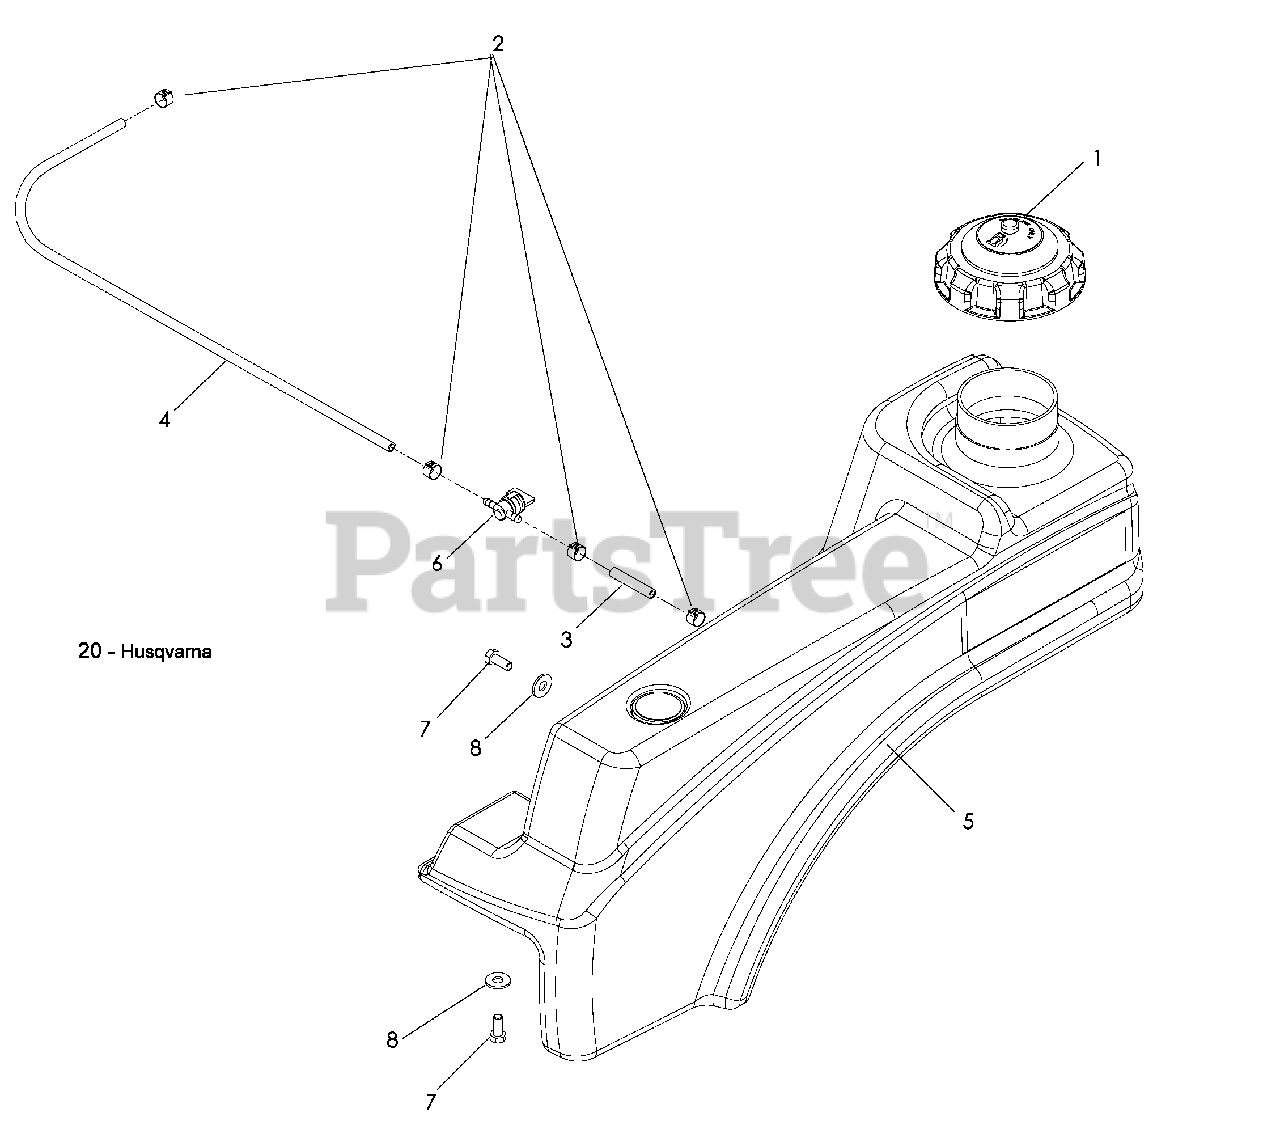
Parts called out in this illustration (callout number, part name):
1	CAP, FUEL
2	FUEL LINE CLAMP
3	HOSE ¼ x 8
4	HOSE ¼ x 28
6	FUEL VALVE
7	HHB 5/16-18 x ¾
8	WASHER 5/16
